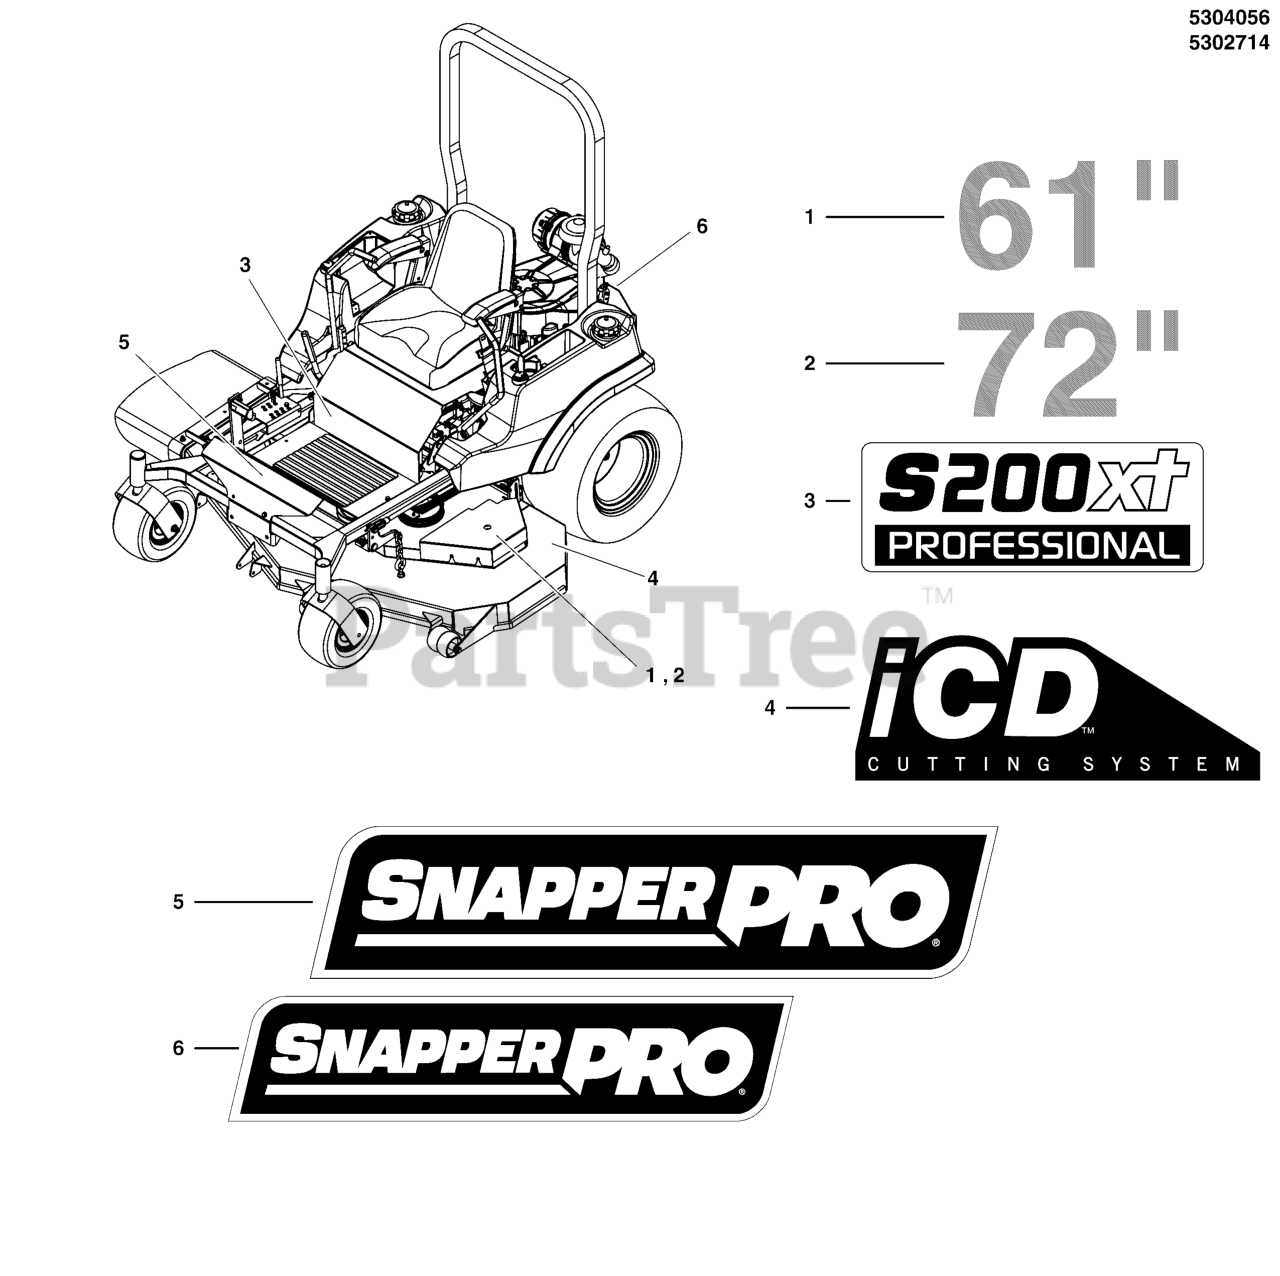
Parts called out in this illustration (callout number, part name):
1	DECAL, 61"
2	DECAL, 72"
3	DECAL, SNAPPER PRO, S200XT (2014)
4	DECAL, iCD CUTTING SYSTEM
5	DECAL, SNAPPER PRO LOGO, LARGE
6	DECAL, SNAPPER PRO LOGO, MEDIUM
